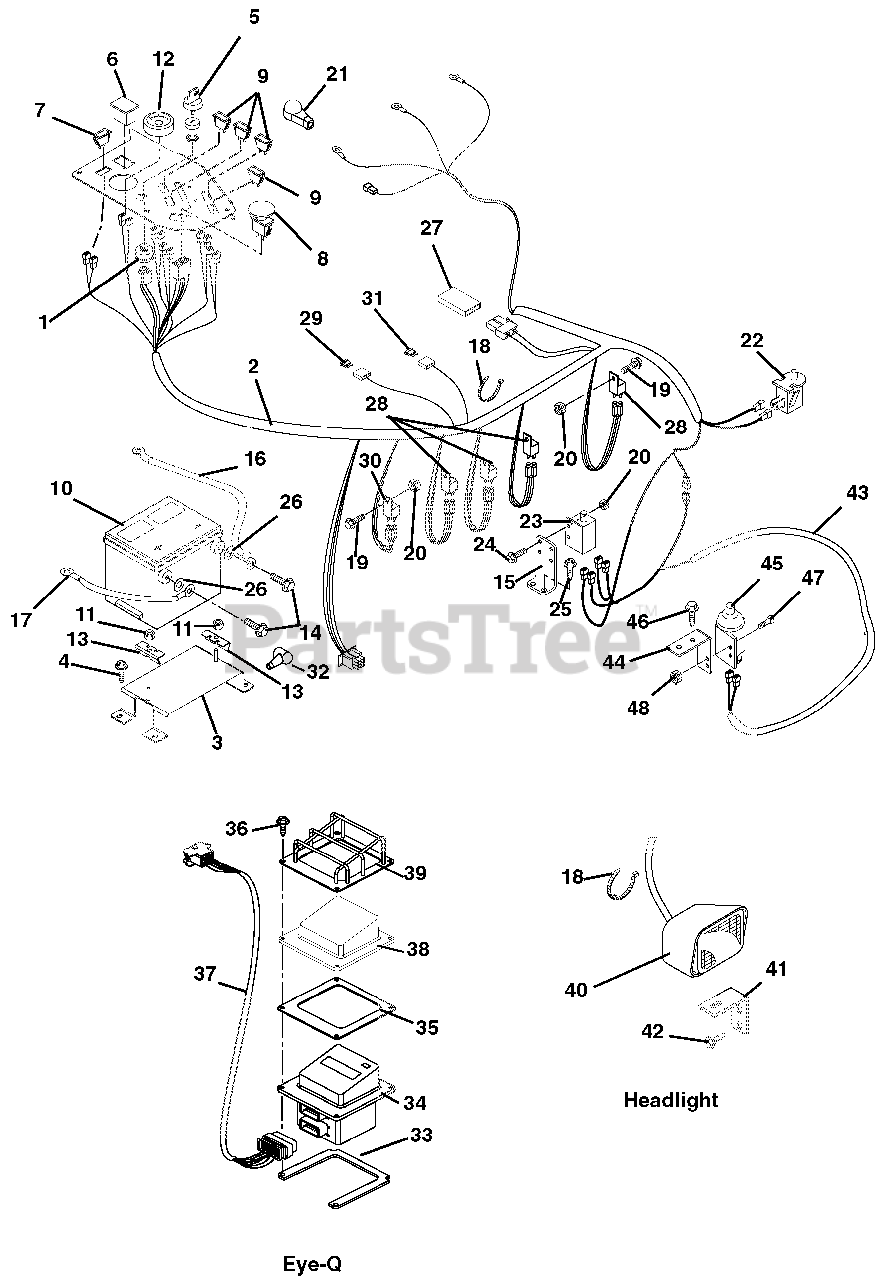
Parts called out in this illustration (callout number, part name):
1	Switch, Ignition
2	Harness, Wiring
3	Weldment, Battery Support
4	Screw, Tapping .38-16 x .75 Hex Washer Head
5	Key, with Cap
6	Hour Meter
7	Switch, Light
8	Switch, Clutch With Retainer Ring
9	Light, Indicator
10	Battery with Tube
11	Nut, Locking Top Flange .31-18
12	Gauge, Temperature
13	Bracket, Battery Hold-Down
14	Bolt, Hex .25-20 x .75 Grade 5
15	Mount, Safety Switch
16	Positive Cable w/Boots
17	Cable, Negative Battery
18	Cable Tie
19	Screw, Machine 10-24 x .75 Hex Washer Head
20	Nut, Locking Nylon 10-24 With Insert
21	Boot, Terminal, Red
22	Switch, Snap Mounting (N.O.) (Included with Seat)
23	Switch, Single Pole
24	Screw, Machine 10-24 x .75 Hex Washer Head
25	Screw, Tapping .25-20 x .50 Hex Washer Head
26	Washer, Flat Steel .406 x 1.00 x ..083
27	Diode, Connector Shell
28	Relay (Included with Harness)
29	Fuse, ATO 30 Amp (Included with Harness)
30	Pre-Heat Timer (Included with Engine)
31	Fuse, ATO 60 Amp (Included with Harness)
32	Battery Terminal Boot, Red
33	Spacer, Enclosure Mounting (Bottom)
34	Assembly, Eye-Q – Enhanced
35	Gasket, Eye-Q
36	Screw, Machine 10-24 x 1.0 Slotted Pan Black
37	Harness Jumper (Eye-Q)
38	Guard, Element
39	Guard, Eye-Q
40	Headlight
41	Bracket, Headlight Mounting
42	Screw, Tapping, .38-16 x .50 Hex Washer Head
43	Harness, Wire Adapter, CE
44	Switch, Mount
45	Switch, Single Pole (N.O.) with Cover
46	Screw,Tapping .31-18 x .50 Hex Washer Head
47	Screw, Machine 10-24 x .75 Hex Washer Head
48	Nut, Locking, Nylon 10-24 with Insert
